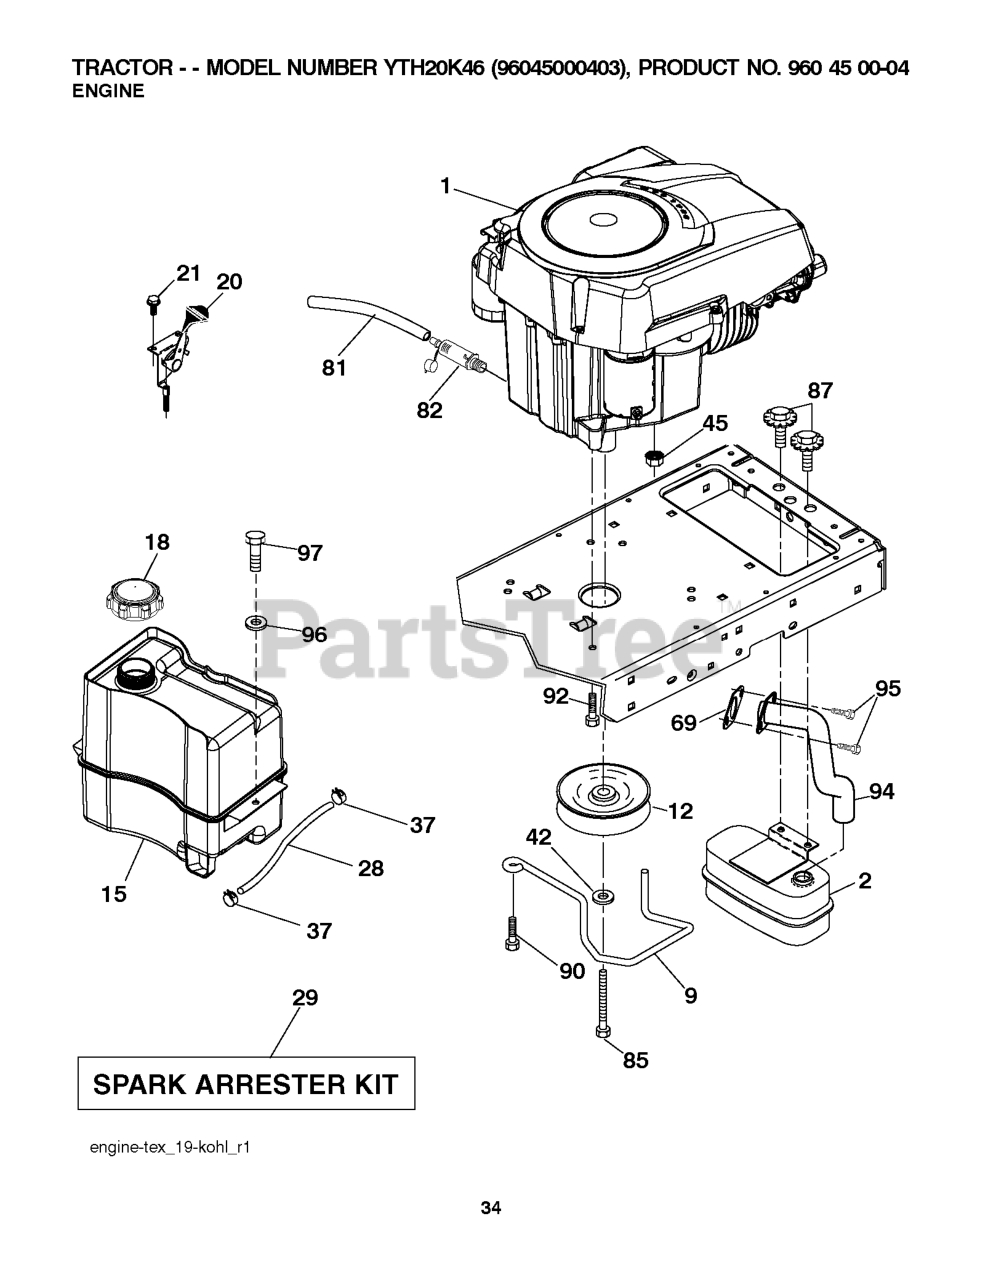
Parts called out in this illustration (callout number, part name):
2	MUFFLER.SINGLE.CYL.KOHL/B&S
9	KEEPER.BELT.ENGINE.3.25 (3 2)
12	PULLEY.ENGINE.5.0.PD
15	TANK.ASM.FUEL.FR.2.5GA.
18	FUEL CAP
20	CONTROL.TH/CK.COBRA.KO
21	SCREW
28	LINE.FUEL.20"FRONT.EMI
29	KIT.SPARK ARRESTOR 794945 B&S
37	HOSE CLAMP
42	LOCKWASHER
45	NUT
69	GASKET.EXHAUST.KOHLER
81	TUBE, DRAIN OIL ASM.
82	PLUG DRAIN OIL EASY
85	BOLT HEX 7/16-20X4-1/4"
87	BOLT 5/1618UNC X 3/4 W/ SEMS
90	SCREW 3/8-16X1
92	SCREW 3/8-16X1
94	RP.TUBE.EXHAUST.KOHL.COURAGE
95	SCREW.SOCKET HD.5/16-1
97	SCREW HEXWSHR 1/4-20X3/4
